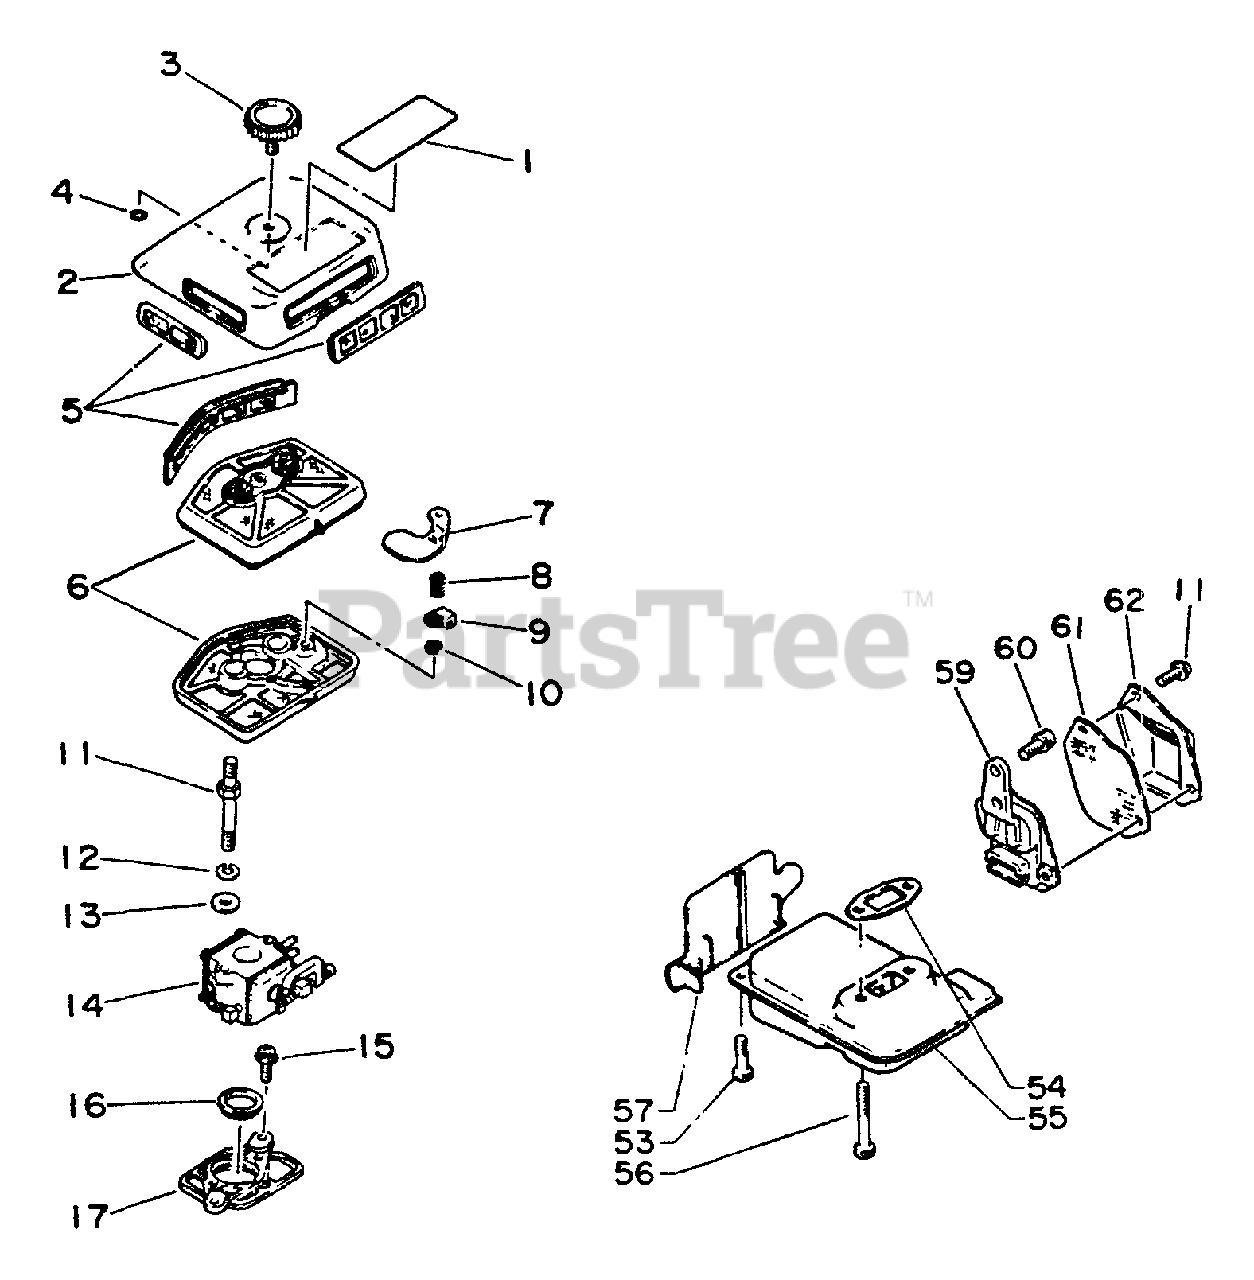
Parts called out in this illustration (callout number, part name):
1	LABEL - MODEL
2	COVER, AIR FILTER
3	THUMBSCREW
4	O-RING 3
5	DEBRIS FILTER KIT
6	FILTER, AIR
7	SHUTTER, CHOKE
8	SPRING
9	LEVER, CHOKE
10	E-RING 3
12	WASHER, SPRING 5
13	WASHER
14	CARBURETOR - WA-133
15	SCREW 4×12
16	HOLDER
17	ADAPTER, CARBURETOR
53	BOLT 5×20
54	GASKET, EXHAUST
55	MUFFLER
56	BOLT 5×50
57	INSULATOR
59	ADAPTER
60	BOLT 5×12
61	SCREEN, SPARK ARRESTER
62	GUIDE, EXHAUST
